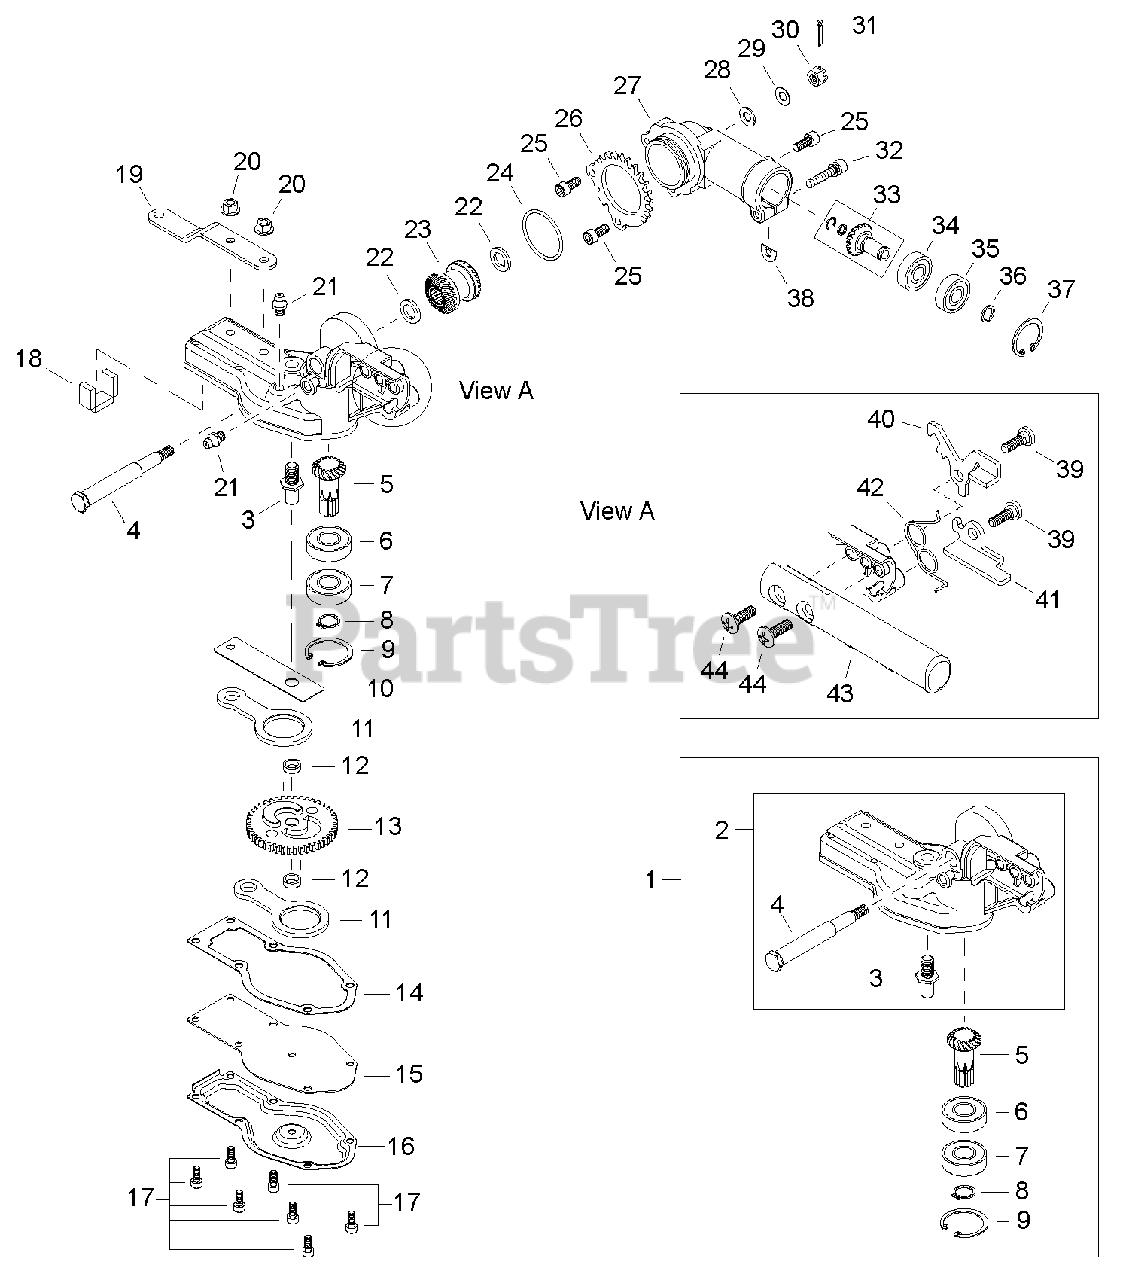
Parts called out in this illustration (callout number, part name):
2	GEAR CASE ASSY
3	PIPE, MAIN
4	SHAFT
5	PINION SHAFT
6	BEARING, BALL - 6001
7	BEARING, BALL - 6001ZZ
8	RING, RETAINING - 12
9	RING, RETAINING - 28
10	PLATE, GUIDE
10-1	GEAR CASE ASSY
11	ROD, CONNECTING
12	SPACER
13	CAM GEAR
14	GASKET
15	SPACER
16	GEARCASE COVER
17	SCREW - 4X10
18	SEAL, FELT
19	BRACKET, CUTTER
20	NUT - 5 -- FLANGE
21	FITTING, GREASE
22	COLLAR
23	GEAR - BEVEL
24	O-RING
25	SCREW - 5X12
26	LOCKING RING
27	UPPER GEARCASE HOUSING
28	WASHER - 6
29	WASHER - CONICAL
30	NUT - CASTLE
31	PIN, SPLIT
32	SCREW - 5X25
33	GEAR - BEVEL
34	BEARING, BALL - 609
35	BEARING, BALL - 609ZZ
36	RING, RETAINING
37	RING, RETAINING - 24
38	SHIM
39	SCREW
40	LEVER, LOCK
41	LEVER, LOCK
42	SPRING
43	CUTTER ADJUSTMENT LEVER
44	SCREW - 6X20
